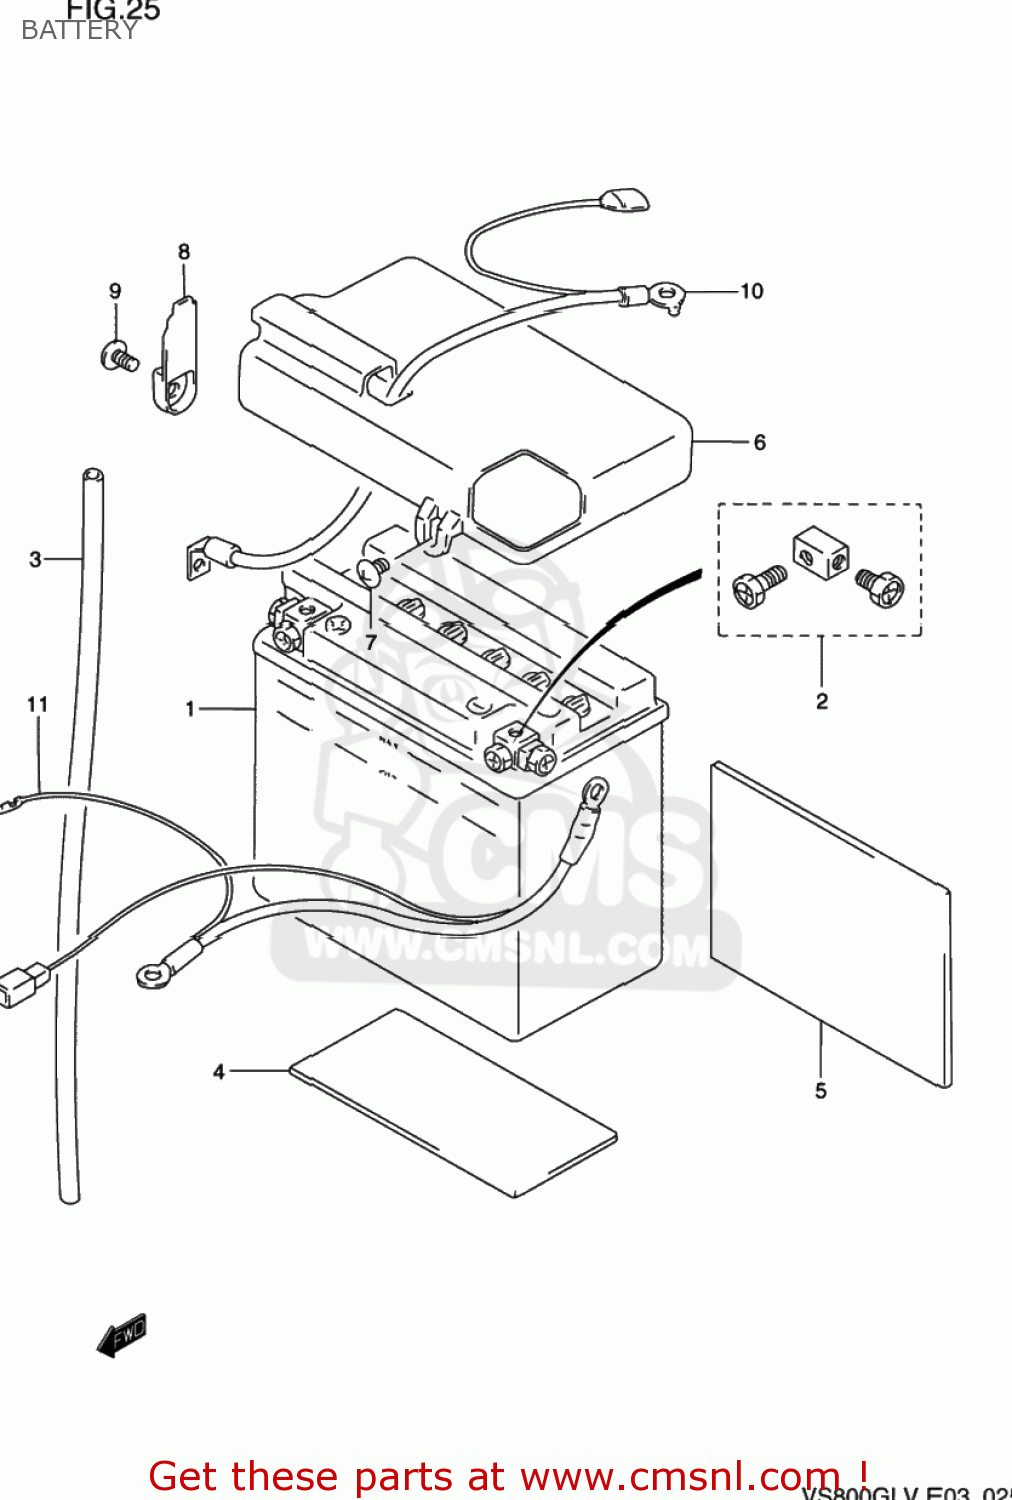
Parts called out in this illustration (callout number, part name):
1	BATTERY ASSEMBLY (12V)
2	BOLT SET,BATTERY TERMINAL
3	HOSE,BATTERY EXHAUST(L:780)
4	PROTECTOR(170X95X3.0)
5	PROTECTOR(80X80X2)
6	COVER,BATTERY UPR
7	SCREW
8	COVER,BATTERY TERMINAL
9	SCREW
10	WIRE,BATTERY PLUS LEAD
11	WIRE,BATTERY MINUS LEAD
